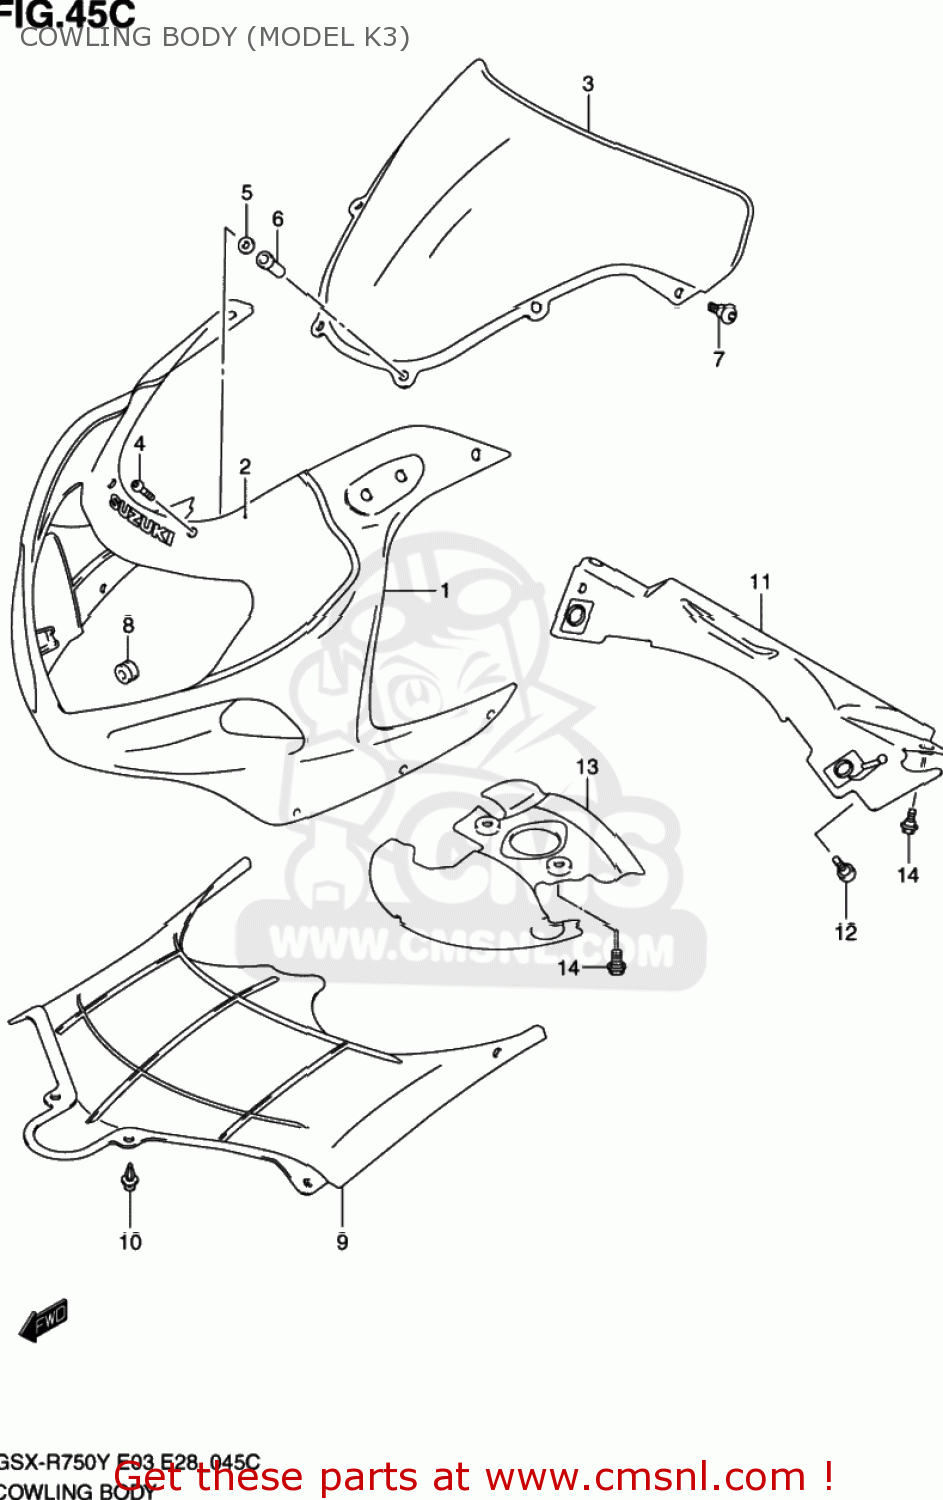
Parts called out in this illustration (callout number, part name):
1	COWLING,BODY(BLUE)
2	TAPE,COWL BODY
3	WINDSCREEN
4	SCREW(5X14)
5	WASHER
6	NUT
7	SCREW(5X16)
8	CUSHION
9	COVER,BODY COWLING
10	CLIP(BLACK)
11	COVER,COWLING FR LWR
12	BOLT(5X16)
13	COVER,LWR BRACKET
14	BOLT
